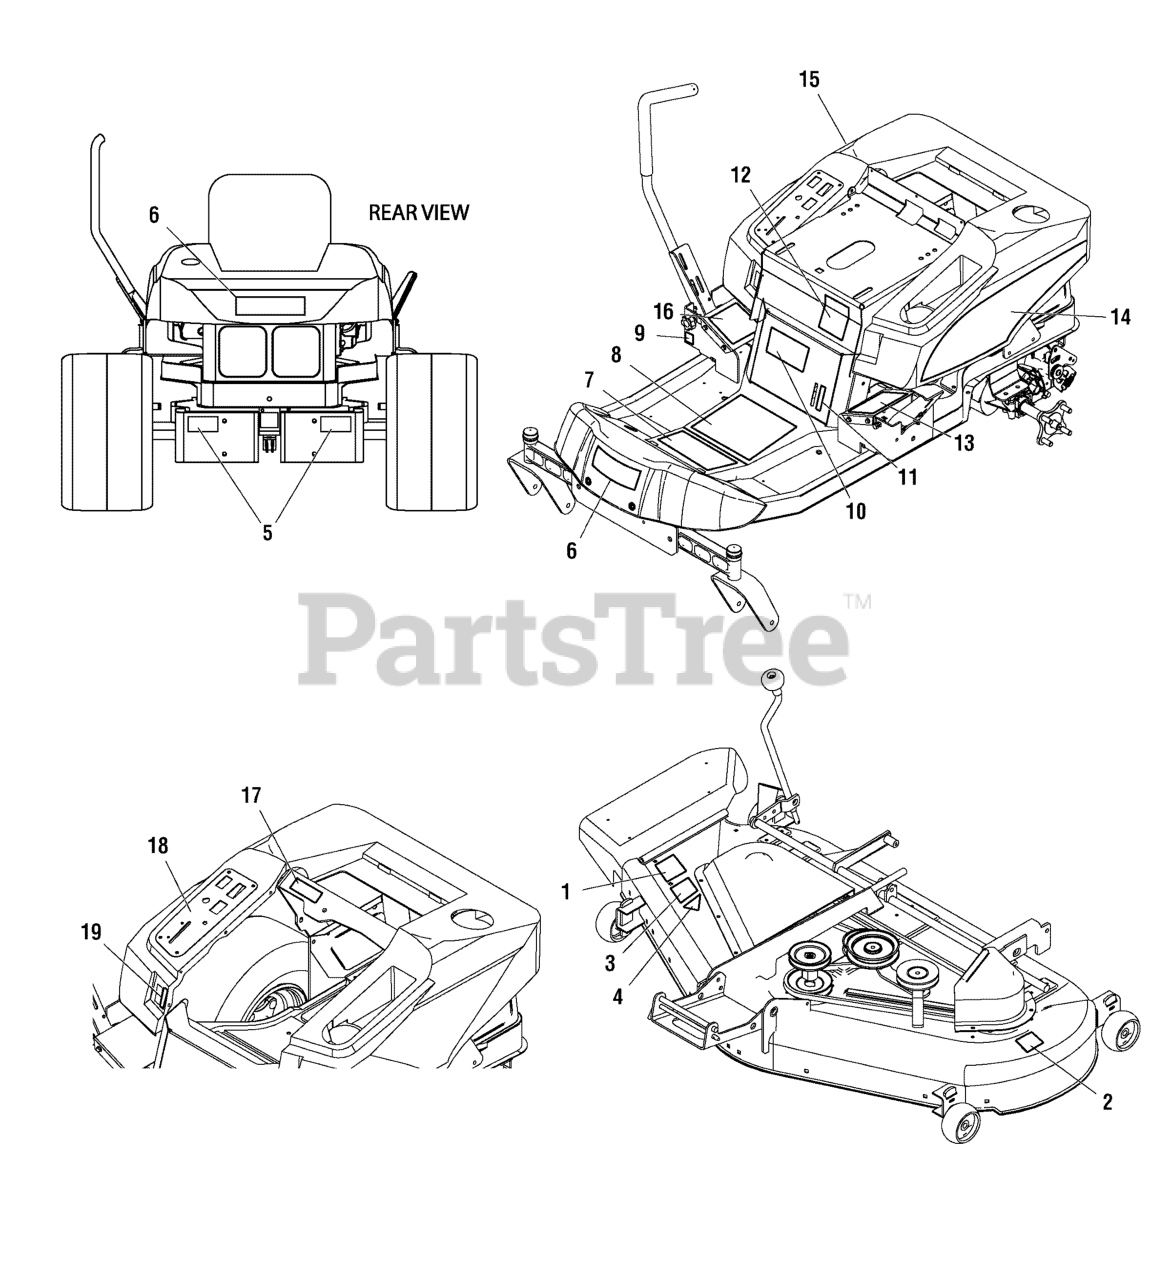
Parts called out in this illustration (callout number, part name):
1	DECAL, Danger Do Not Operate without Deflector
2	DECAL, Danger Do Not Put Hands/Feet in Mower
3	DECAL, 44" 2006 Silver/Black
4	DECAL, OPEI Certified ANSI B71.12003 Gold
5	DECAL, Transmission Release Instructions BM K56
6	DECAL, Craftsman ZTS
7	DECAL, Operator Instructions Front
8	DECAL, Operator Instructions Back
9	DECAL, Tracking Adjustment ZT 7000
10	DECAL, ZTS 7500 20/44
10	DECAL, ZTS 7500 24/50
11	DECAL, Height of Cut
12	DECAL, Service Parts Kohler, 20/44
12	DECAL, Service Parts B&S 24HP
13	DECAL, Handle Control, L.H. ZTS 7500
14	DECAL, Seat Deck L.H. Craftsman ZTS
15	DECAL, Seat Deck R.H. Craftsman ZTS
16	DECAL, Handle Control R.H. SEARS ZTS 7500
17	DECAL, Do Not Remove Foam Around Engine
18	DECAL, Instrument Panel SEARS ZTS 7500
19	DECAL, Height of Cut SEARS ZTS 7500
